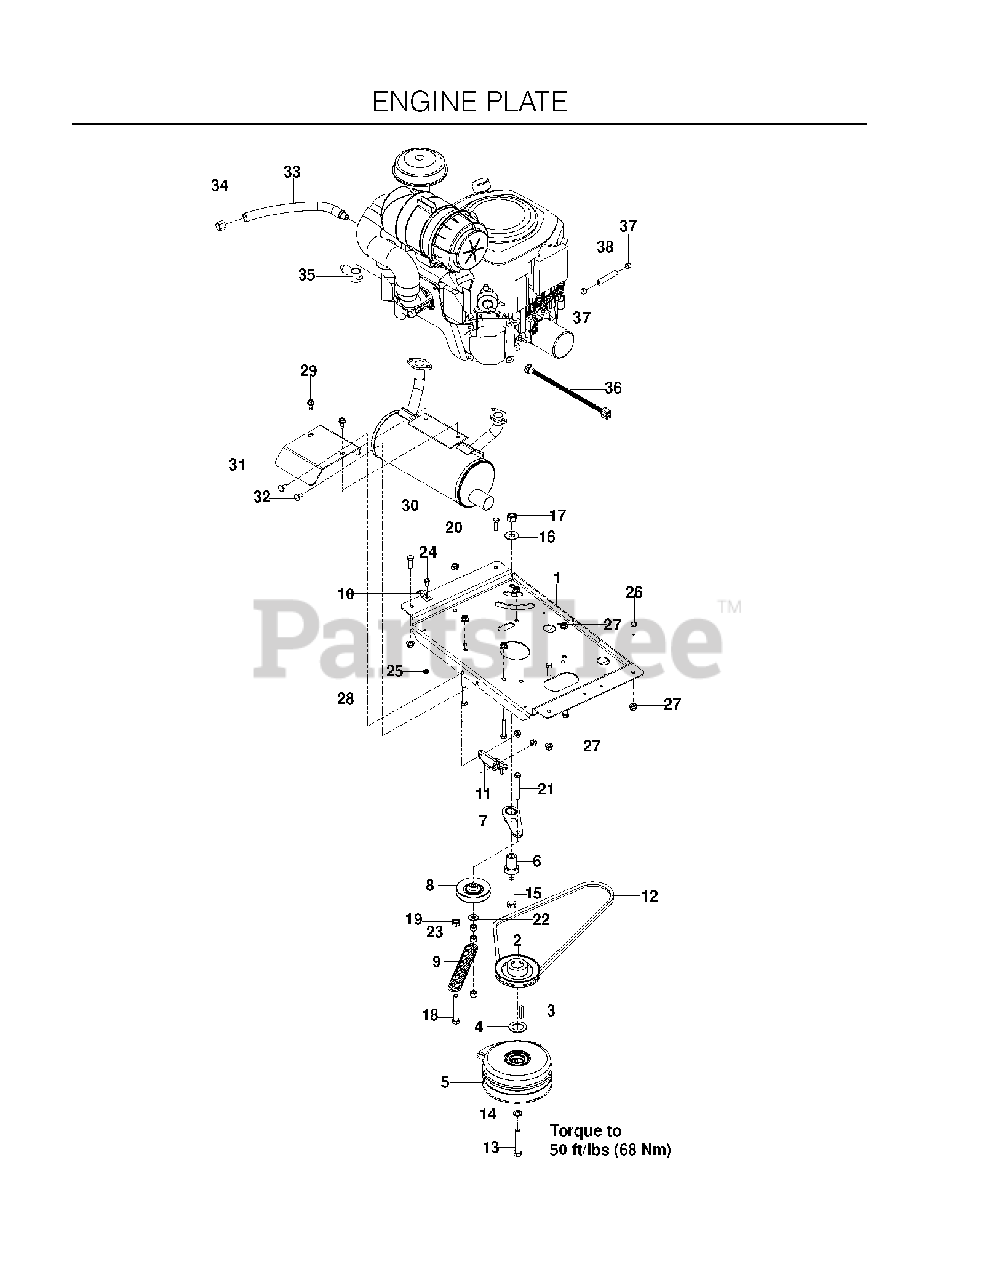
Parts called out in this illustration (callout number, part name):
1	PLATE, ENGINE, BLK
3	KEY, 1/4 SQ X 1 1/4
4	WASHER, 1.025 ID X 1.64
5	CLUTCH, 200 FT/LB
6	IDLER SPINDLE
7	IDLER ARM WELDMENT
8	PULLEY, IDLER 3 METAL
11	STOP, CLUTCH
12	BELT, "A", 44.0"
13	BOLT 7/16F X 2 1/2
14	WASHER 7/16 LOCK
15	HCS 1/2C X 2 3/4
16	WASHER 1/2 FLAT
17	NUT 1/2-13 HEX NYLOC ZD
18	SCREW 3/8C X 2 3/4 HEX CAP
19	NUT 3/8C WHIZ
20	NUT 3/8C CENTERBLOCK
21	HCS 3/8-16 X 2-1/2 TPBLT
22	WASHER 5/16 FLAT
23	NUT 3/8-16 NYLOC
24	HCS 1/4-20.
25	JAM NUT 1/4C
26	HCS 5/16C X 1
27	5/16-18 NYLOC FLANGE NUT
28	HCS 5/16C X 1 3/4
29	BOLT 5/16-18 X 3/4
30	Muffler, Kohler Gen II
31	MOUNT, COMMAND MUFFLER, BLK
32	RHSNB 5/16C X 1
33	OIL DRAIN HOSE
34	DRAIN CAP
35	INSULATOR
36	HARNESS, KOHLER 10"
37	HOSE CLAMP
38	FUEL LINE 2.5"
